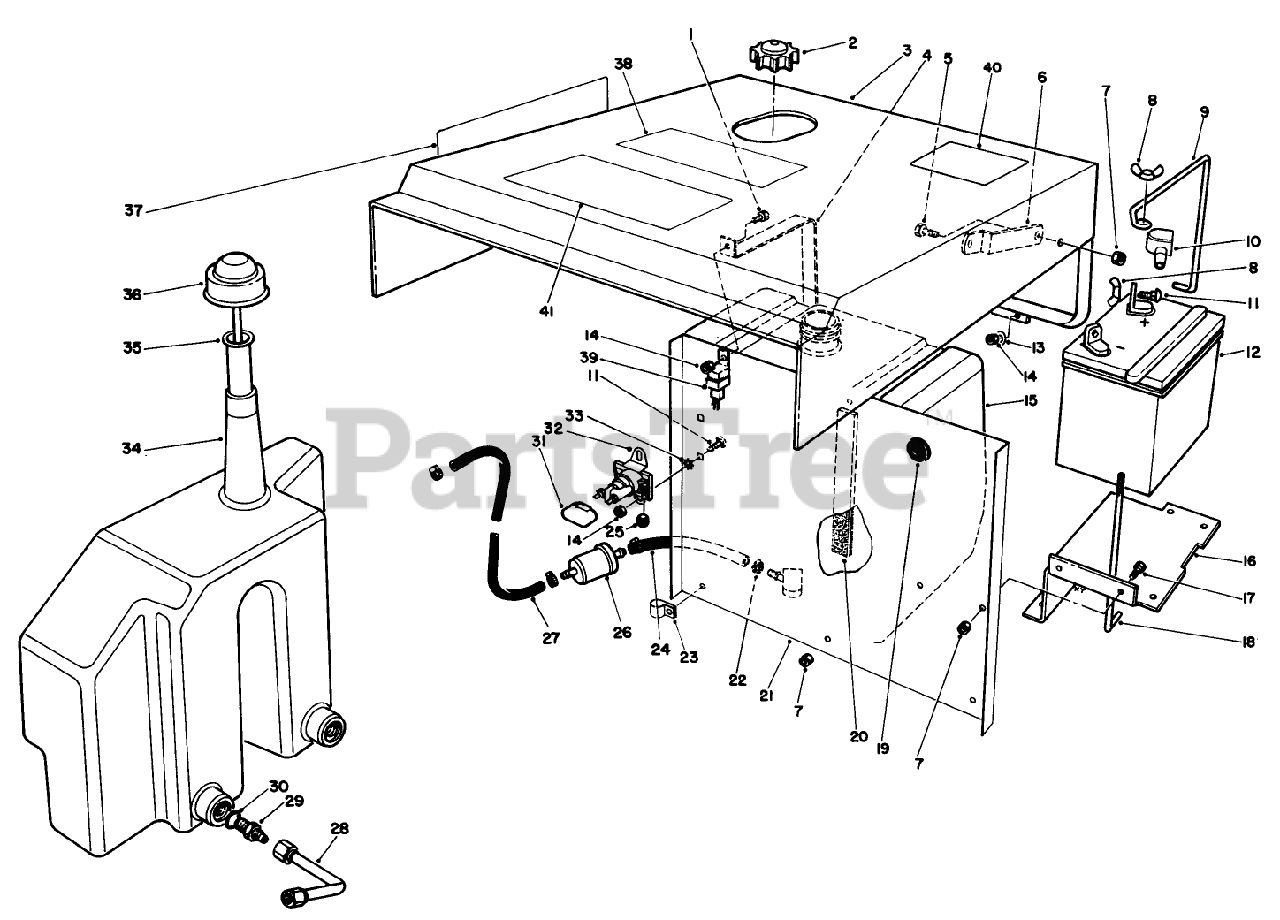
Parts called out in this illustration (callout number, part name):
1	SCREW-HH
2	GAS CAP ASM
3	Hood
4	Strap-Fuel Tank
5	SCREW-HH
6	UPPER HOOD STOP
7	NUT-LOCK, NI
8	NUT-WING
9	BATTERY CLAMP
10	BOOT-TERMINAL, RED
11	BOLT-CARR
12	Battery
13	WASHER-FLAT
14	NUT-LOCK, NI
15	TANK-FUEL
16	Support-Battery
17	SCREW-HH
18	ROD-SUPPORT, BATTERY
19	GROMMET
20	TANK SPONGE
21	HEAT SHIELD B
22	CLAMP-HOSE
23	CLAMP-WORM
24	HOSE-FUEL
25	NUT-HEX
26	FUEL FILTER
27	HOSE-FUEL
28	TUBE ASM
29	Fitting-Hydraulic Straight (Incl. Ref. #30)
30	O-RING
31	SOLENOID COVER
32	SOLENOID
33	WASHER-LOCK/EXT
34	OIL RESERVOIR
35	SCREEN-FILLER
36	CAP WA
37	DECAL - PROLINE 118
38	DECAL-REFUELING
39	RELAY
40	DECAL - SERVICE INSTR.
41	DECAL - CAUTION
